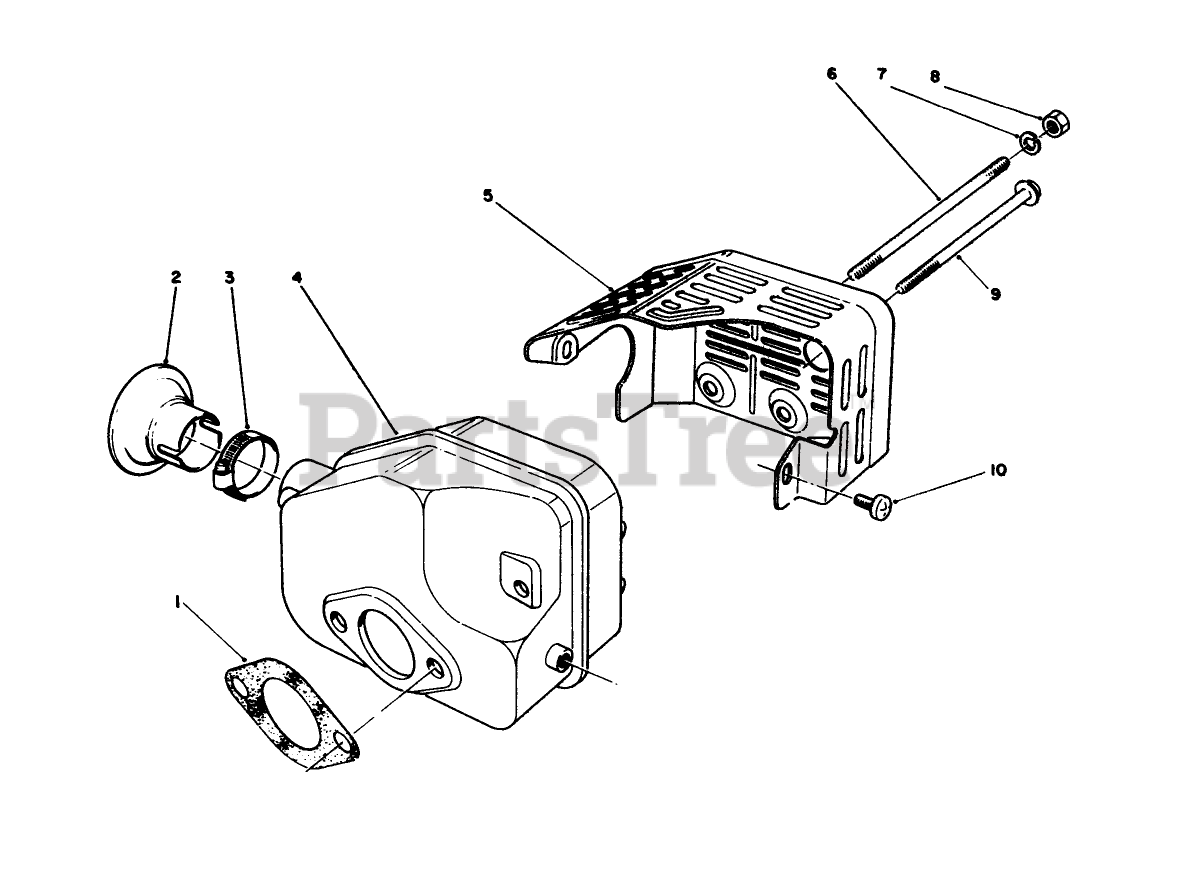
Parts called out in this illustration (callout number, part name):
1	GASKET
3	Clamp
4	MUFFLER
5	COVER-MUFFLER
7	WASHER-LOCK
10	SCREW
